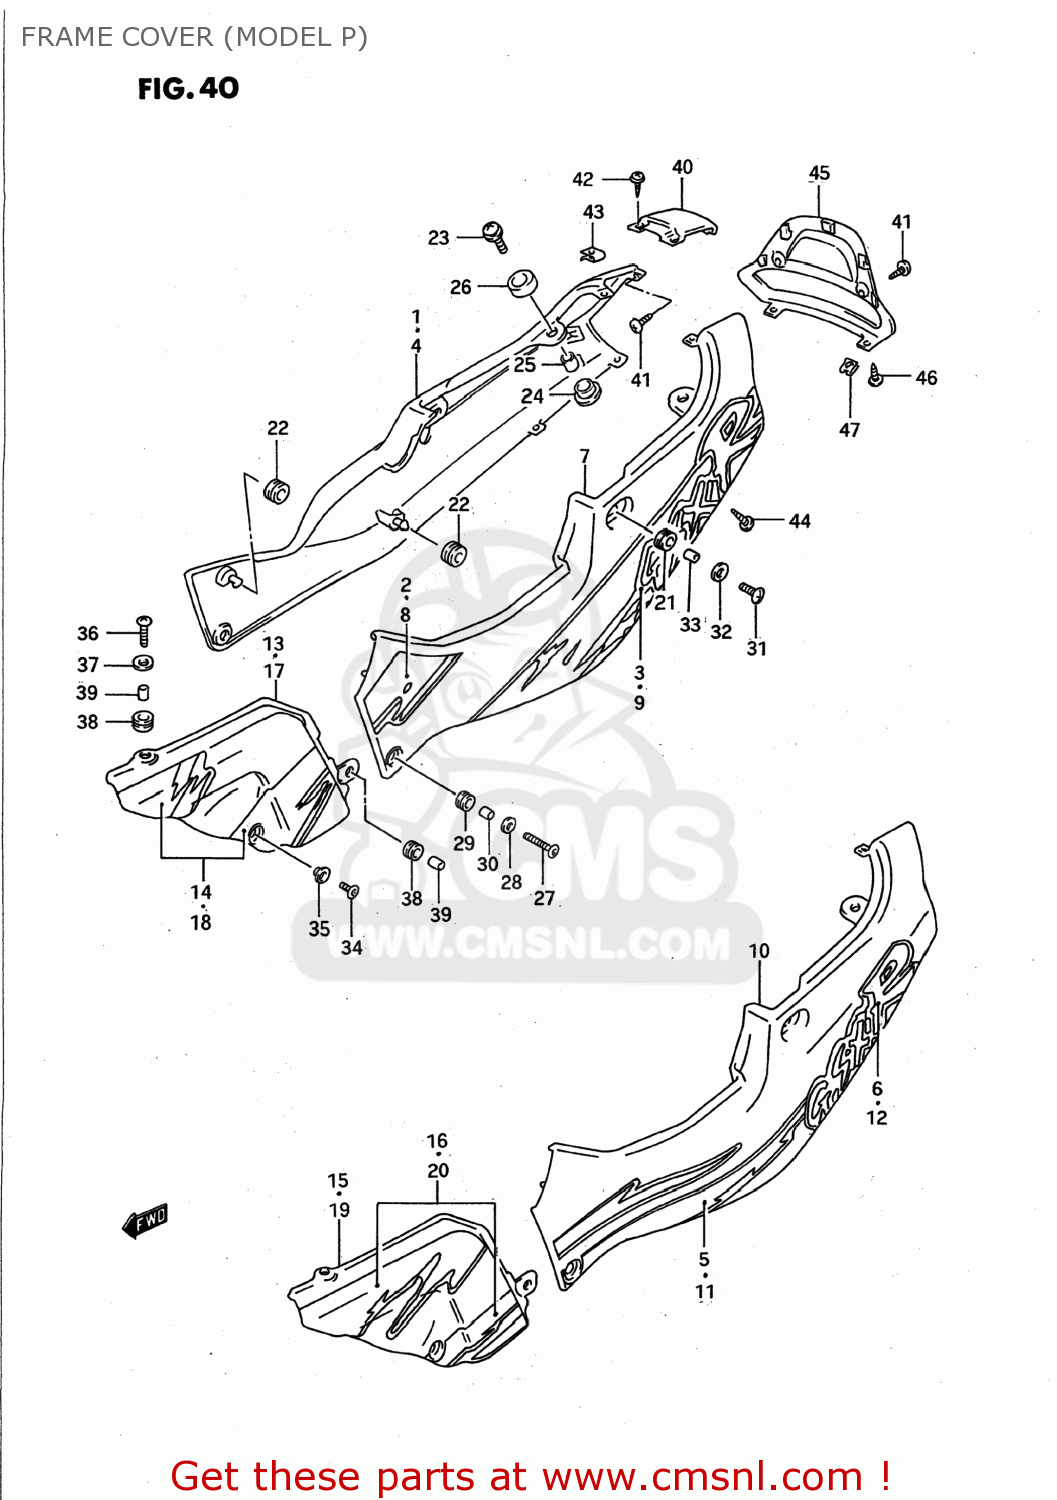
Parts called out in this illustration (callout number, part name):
1	COVER ASSEMBLY,FRAME,RIGHT
2	TAPE,FRAME COVER,UPPER
3	TAPE,FRAME COVER,LOWER
4	COVER ASSY,FRAME,R(BLACK)
5	TAPE SET,FRAME COVER S
6	EMBLEM,FRAME COVER,RIGHT
7	COVER ASSY,FRAME,L(WHITE)
8	TAPE,FRAME COVER,UPPER
9	TAPE,FRAME COVER LWR,L
10	COVER ASSEMBLY,FRAME,LEFT
11	TAPE SET,FRAME COVER STRIPE,L
12	EMBLEM,FRAME COVER,LEFT
13	COVER ASSY,FRAME BODY,R
14	TAPE SET,FRAME COVER B
15	COVER ASSY,FRAME BODY,R
16	TAPE SET,FRAME COVER B
17	COVER ASSEMBLY,FRAME BODY
18	TAPE SET,FRAME COVER B
19	COVER ASSEMBLY,FRAME BODY
20	TAPE SET,FRAME COVER B
21	CUSHION
22	CUSHION
23	SCREW(6X30)
24	CUSHION,FRAME COVER LWR
25	SPACER
26	CUSHION,TAIL COVER UPR
27	SCREW(6X30)
28	WASHER
29	CUSHION
30	SPACER (6.1X9X9)
31	SCREW(6X20)
32	WASHER(6,5X22X1.6)
33	SPACER (6.3X9.1X6.7)
34	SCREW(5X14)
35	WASHER
36	SCREW(6X25)
37	WASHER (6.5X18X1.6)
38	CUSHION
39	SPACER (6.1X9X9)
40	COVER ASSY,FRAME CTR
41	SCREW(5X12)
42	SCREW
43	NUT
44	SCREW
45	COVER,FRAME RR
46	SCREW(5X12)
47	NUT
